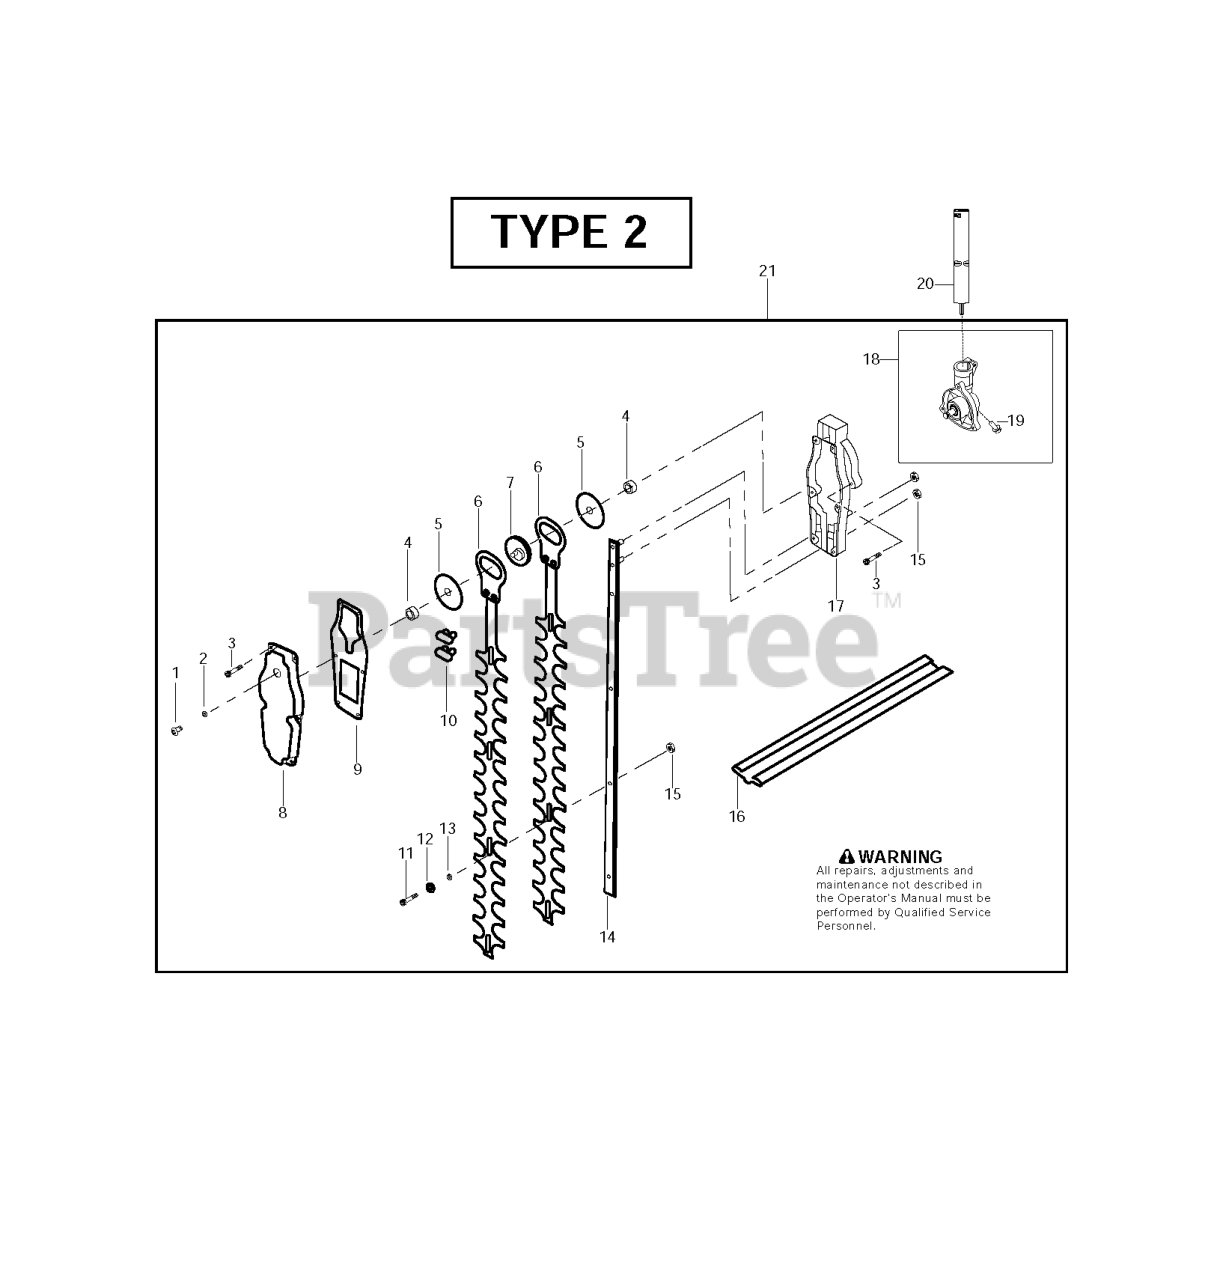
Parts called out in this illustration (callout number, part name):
3	SOCKET SCREW FLANGE KAAZ
5	FIXING PLATE
7	GEAR
9	PACKING KAAZ
10	Felt Packing
12	Conical Spring Washer (M6)
13	CUTTER WASHER KAAZ
14	BLADE GUIDE
15	U-HEXAGON NUT FLANGE KAAZ
20	ASSY TUBE HEDGE TRIMMER
21	GEAR BOX ASSY
